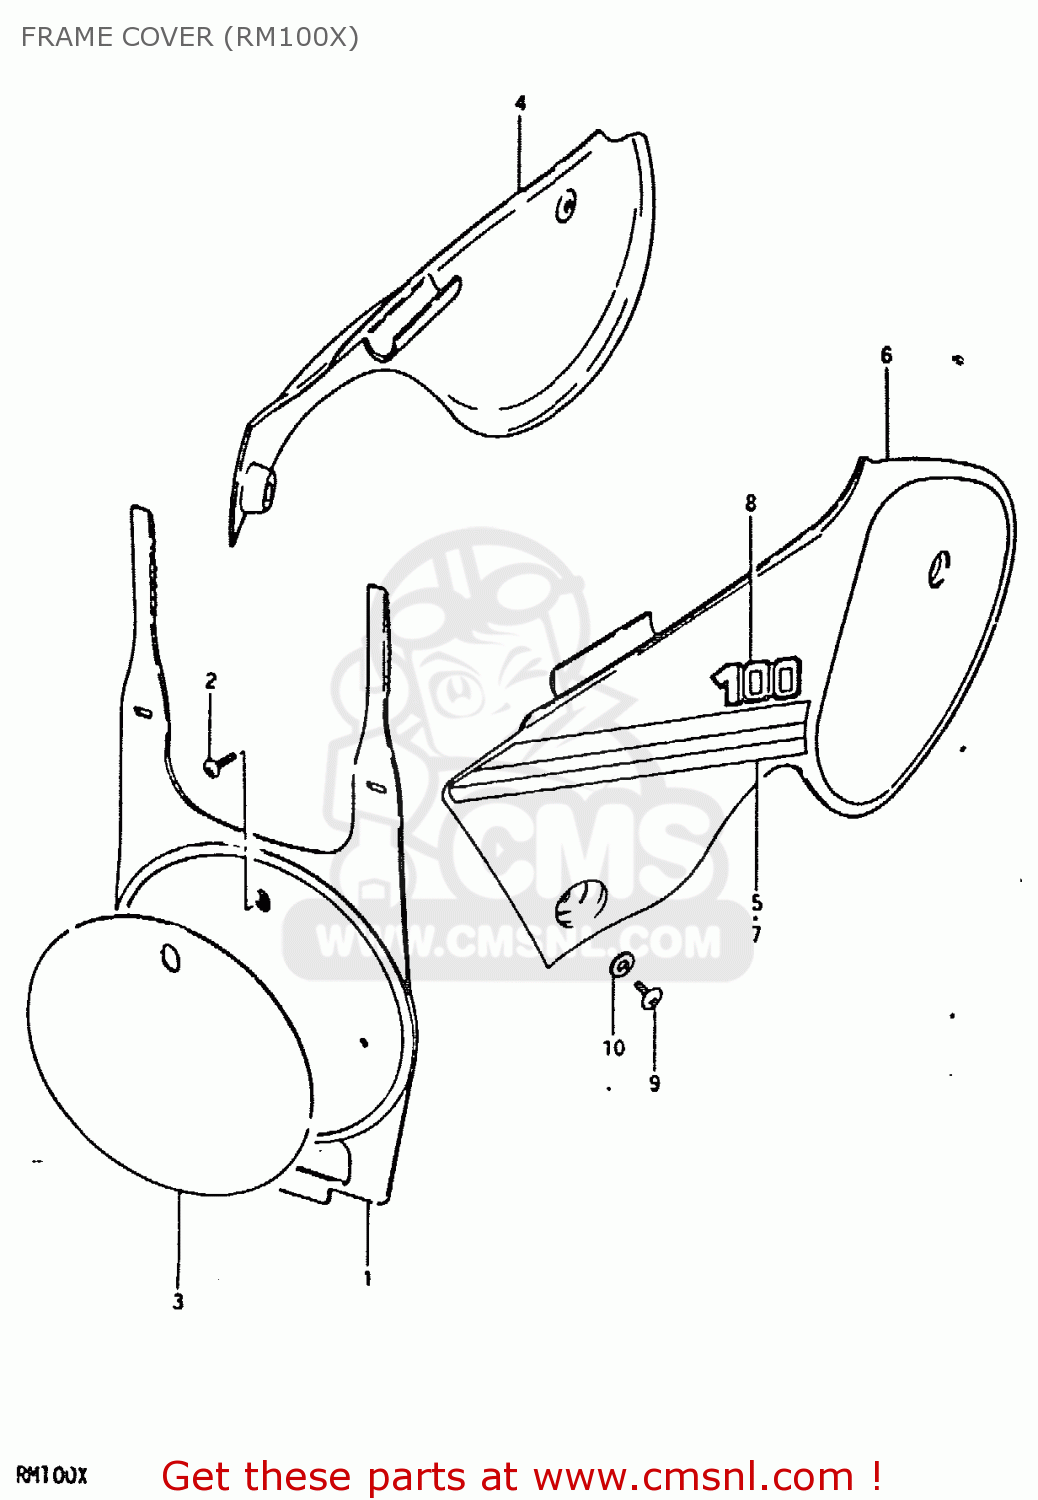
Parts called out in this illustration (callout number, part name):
1	PLATE,NUMBER,FRONT
2	(5X20) CROSS SCREW
3	EMBLEM,FRONT NUMBER PLATE
4	COVER,FRAME,RIGHT
5	TAPE, RH
6	COVER,FRAME,L(YELLOW)
7	TAPE, LH
8	EMBLEM
9	SCREW
10	WASHER
